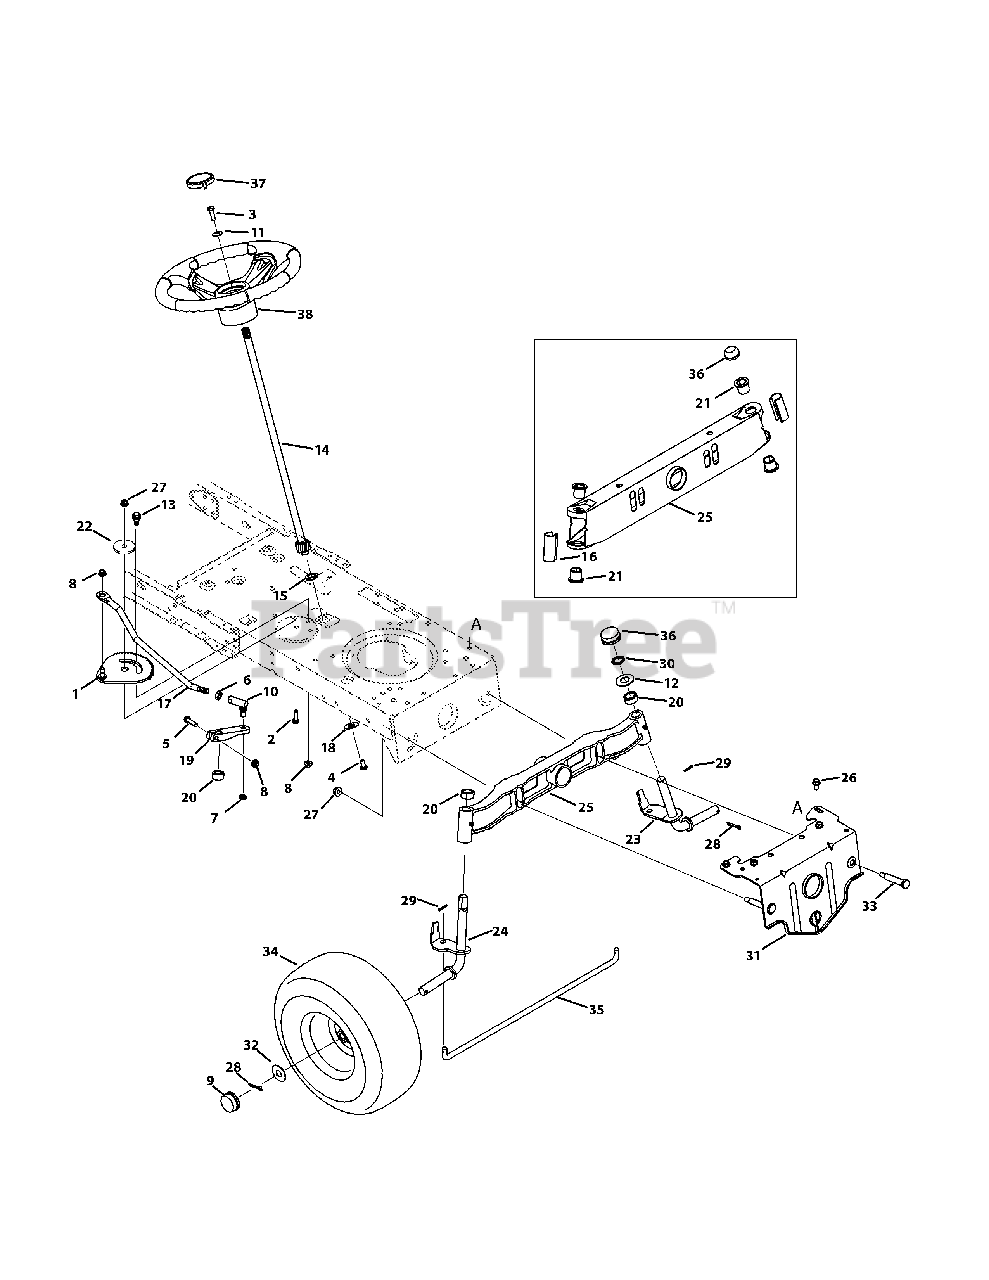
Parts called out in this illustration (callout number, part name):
1	Front Steering Gear Assembly
2	Hex Screw, 3/8-16 x 1.00
3	Screw, 5/16-18, 1.00, Gr5, Lock
4	Screw, Mach, 5/16-18, 0.750
5	Screw, 5/16-18, 1.75, Gr5
6	Nut, Jam, 7/16-20, Gr2
7	Nut, Hex Lock, 3/8-24
8	Nut, Flange Lock, 5/16-18, Grf
9	Hub Cap
10	Ball Joint, 7/16-20, Lock
11	Washer, Bell, .340 x .872 x .060
12	Washer, Flat, .78 x 1.59 x .60
13	Shoulder Screw, .435 x .3485, 5/16-18
14	Steering Shaft, 5/8 Spline x 21.86
15	Bearing, Flange, Hex 5/8
16	Std. Axle Cap
17	Steering Link
18	Cap, 1.25 x .16
19	Steering, Block
20	Spacer, .710 ID x .125 OD x .56
21	Bearing, Flg.
22	Shoulder Spacer, .884 x .190
23	Axle Assmbly LH (42" Deck)
23	Axle Assembly, LH (46" Deck)
24	Axle Assmbly RH (42" Deck)
24	Axle Assembly, RH (46" Deck)
25	Pivot Bar, Cast
25	Pivot Bar
26	Screw, 5/16-18, 0.750
27	Nut, Flange Lock, 3/8-16, GrF
28	Pin, Cotter, 5/32, 1.25
29	Pin, Cotter, 1/8 x 0.75
30	Push Nut 3/4 Dia.
31	Pivot Bar Bracket
32	Washer, Flat, .781 x 1.59
33	Screw, Shlder, .500 x 2.380, 3/8-16
34	Wheel Ass’y, 15 x 6 x 6 - Grey
34	Wheel Ass’y, 15 x 6 x 6 - Yellow
35	Tie Rod
36	Push Cap, Cast
36	Push Cap
37	Cap, Steering Wheel (Sprig Logo)
37	Cap, Steering Wheel (No Sprig)
38	Steering Wheel, Standard Grip
38	Steering Wheel Soft Grip
